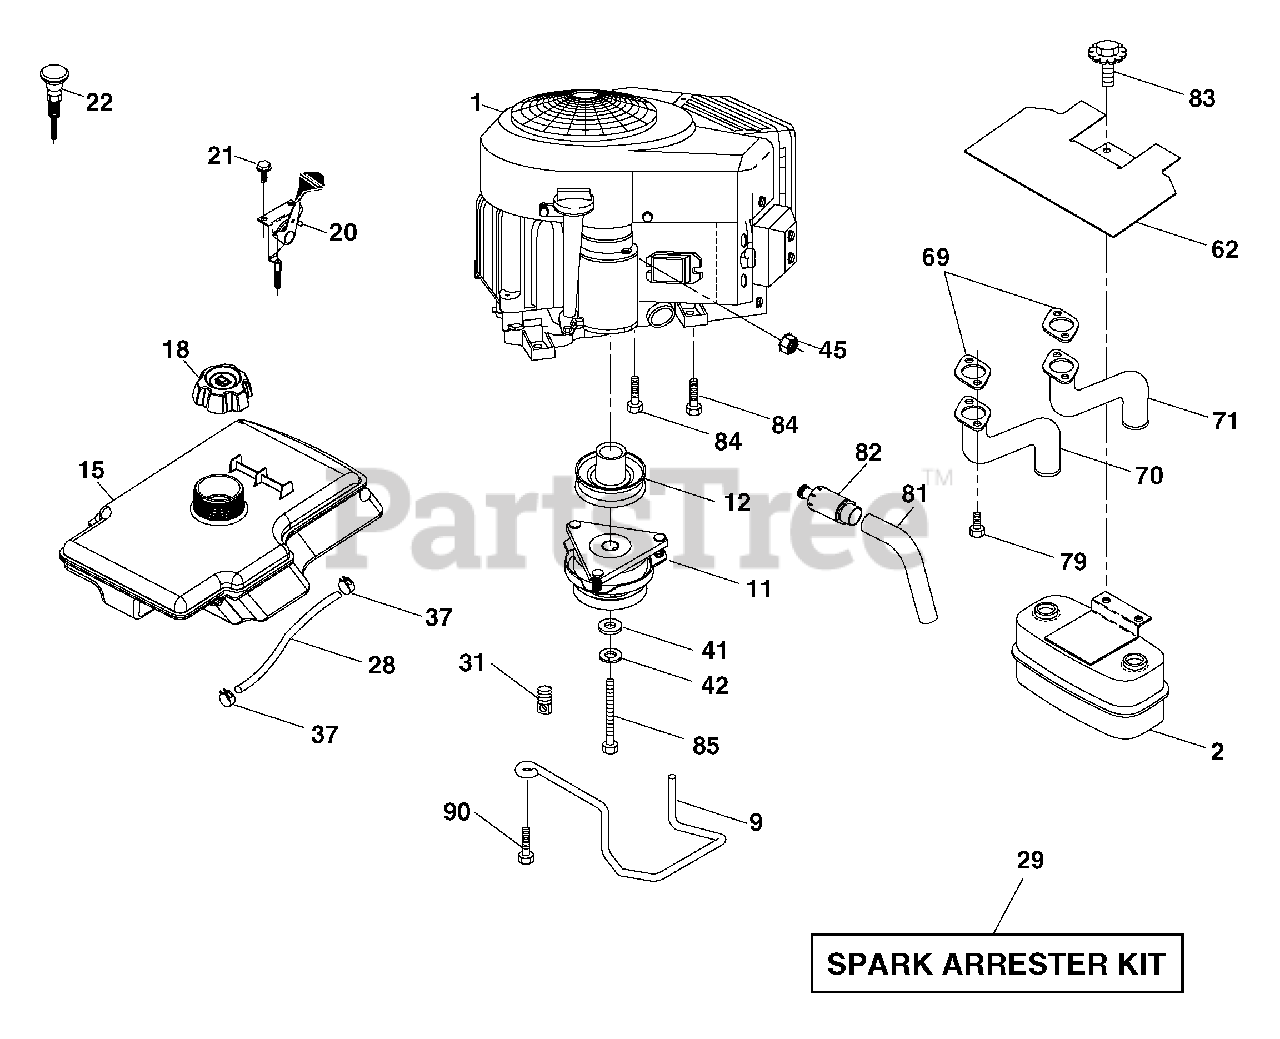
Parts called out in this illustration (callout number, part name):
9	Keeper Belt Engine
11	Clutch Ogura
12	Pulley Engine
15	Tank Fuel
18	Cap Asm
20	Control Throttle
21	Screw 10 x 3/4 Single Lead-Hex
22	Control Choke
28	Fuel Line
29	Spark Arrester Kit
31	Clip Push-In Hinged
37	Clamp Hose
41	Washer 1-1/2 OD x 15/32 ID x .250
42	Washer Lock 7/16
45	Nut Keps Hex 1/4-20 unc
62	Shield Heat Muffler
70	Exhaust Tube LH
71	Exhaust Tube RH
79	Screw Socket Head 5/16-18 x 1
81	Tube Drain Oil Easy
82	Plug Drain Oil
83	Bolt 5/16-18 x 3/4
84	Screw 3/8-16 x 1-1/4
85	Bolt Hex 7/16-20 x 4 x Gr. 5-1.5 Thr
90	Screw 3/8-16 x 1
